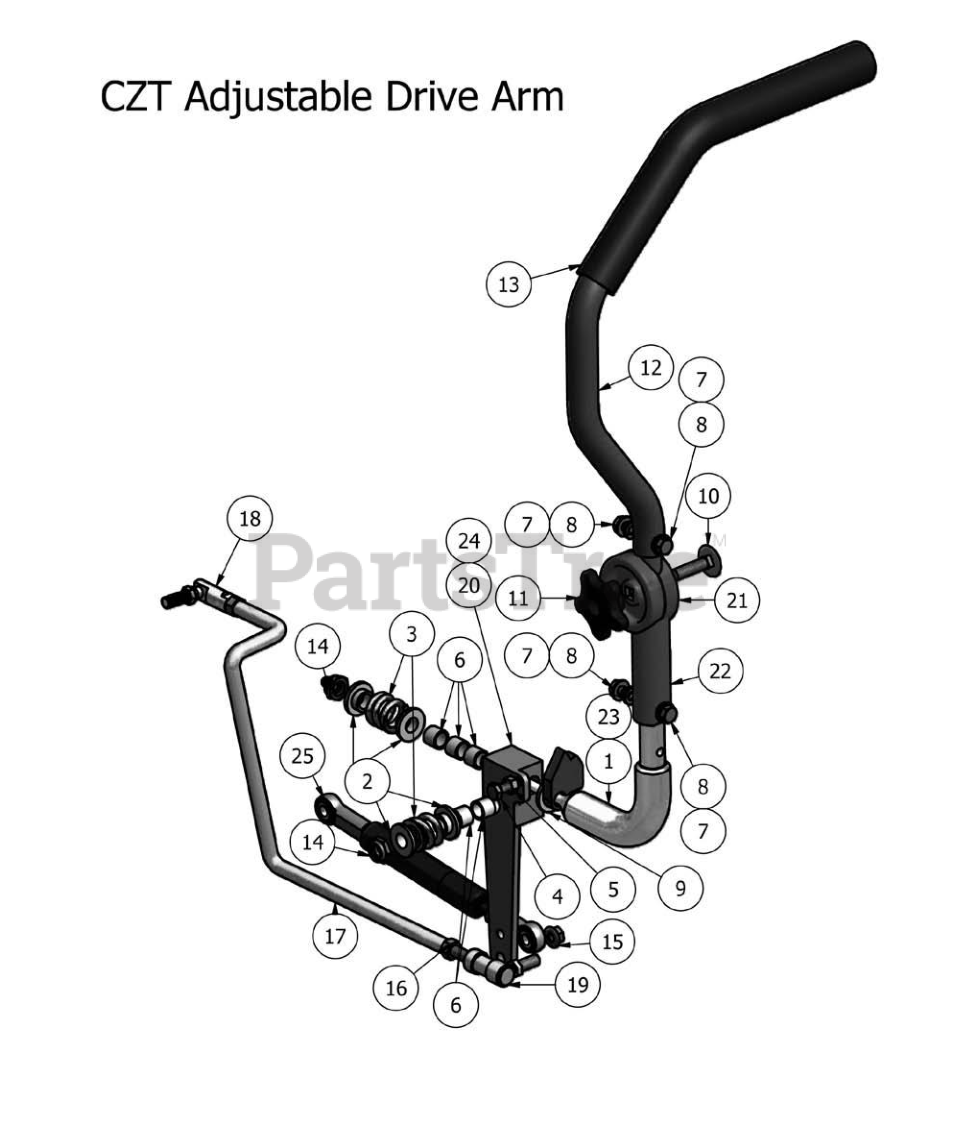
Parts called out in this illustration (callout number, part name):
1	Steering Arm Base-Right
2	.515 ID Nylon Shoulder Washer
3	Drive Lever Spring
4	5/16" x 3/4" Hex Bolt
6	.507 ID Nylon Bushing
7	5/16" Lock Washer
8	5/16" x 1/2" Flange Bolt
9	.635 ID Plastic Washer
10	3/8" x 1-1/4" Carriage Bolt
11	Black Knob for Adjustable Steering Arm
12	Upper Steering Arm Tubing-Adjustable
13	Black Steering Grips
14	1/2" Nylock Nut
15	5/16" Flange Nut
16	3/8" Fine Threaded Jam Nut
17	Transaxle Drive Rod (Right)
18	3/8-24 Ball joint (female/male)
19	3/8-24 Quick Release Ball Joint
20	Drive Arm Lever Housing (Left)
21	Lower Adjuster for Steering Arm
22	Upper Adjuster for Steering Arm
23	Steering Arm Base-Left
24	Drive Arm Lever Housing (Right)
26	Transaxle Drive Rod (Left)
